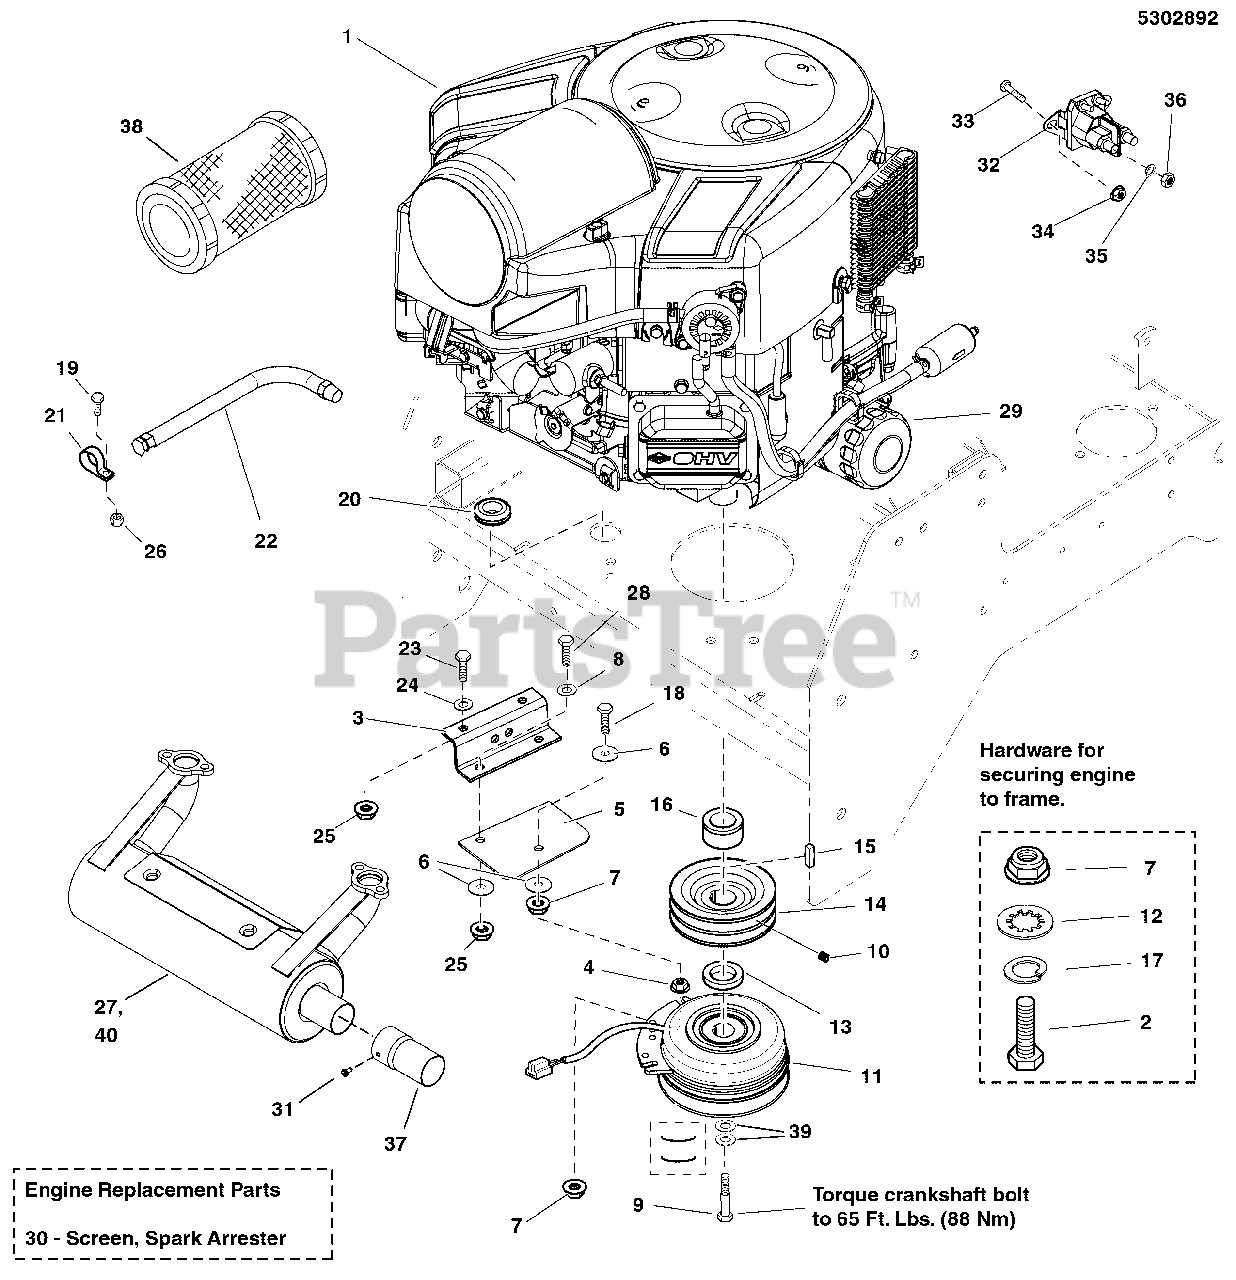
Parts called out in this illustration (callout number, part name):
1	* ENGINE, BRIGGS AND STRATTON
2	BOLT, 5/16-18 X 1-3/4 GD5 YZ
3	ANCHOR, CLUTCH - BLK
4	NUT, 5/16-18 HEX SERRATED FLANGE, LARGE
5	CLUTCH ANCHOR PAD
6	WASHER, .34 X 1.25 X 10 GA
7	NUT, 5/16-18 HEX NYLOCK FLANGE
8	WASHER, 5/16" SAE
9	BOLT, CRANKSHAFT, 7/16" X 2-3/4
9	BOLT, CRANKSHAFT, 7/16" X 2-1/2
10	SET SCREW, 5/16-18 X 3/8, KNURL, W/PATCH
11	CLUTCH,5218-134, WARNER
12	WASHER, 5/16" INT. TOOTH LOCK
13	SPACER, 1.13 X 1.75 X .50
14	PULLEY, CRANKSHAFT (DOUBLE A)
15	KEY, 1/4 SQ. X 1.00
16	SPACER, 1.13 X 1.75 X 1.09, PM
17	WASHER, 5/16" LOCK
18	BOLT, 5/16-18 X 3", FLT
19	BOLT, 1/4-20 X 1" GD5 CZ
20	GROMMET, 7/8
21	CLAMP, VINYL
22	HOSE-OIL DRAIN .375ID 16.5L
23	BOLT, 3/8-16 X 1 GD5 YZ
24	WASHER, 3/8 SAE
25	NUT, 3/8-16 HEX NYLOCK FLANGE
26	NUT, 1/4-20 HEX NYLOCK FLANGE (5025391)
27	MUFFLER, EXHAUST ASSY
28	BOLT, 5/16-18 X 1 GD5 YZ
29	FILTER, OIL, BRIGGS & STRATTON
31	SCREW,SELF-TAP,#8-32 X 3/8,WASH HEX, CZ
32	SOLENOID-4 POLE 12 VOLT DC (TROMBETTA)
33	BOLT, 1/4-20 X 3/4 GD5 YZ
34	NUT, 1/4-20 HEX SERRATED FLANGE
35	WASHER, Light Lock, 5/16
36	NUT, Hex Jam, 5/16-24
37	EXTENSION, TAILPIPE, 3" - BLK
38	FILTER-AIR CLEANER
39	BELLEVILLE WASHER 1.1875 X .442 X .089
40	MUFFLER, RIGHT OUTLET ASSY
